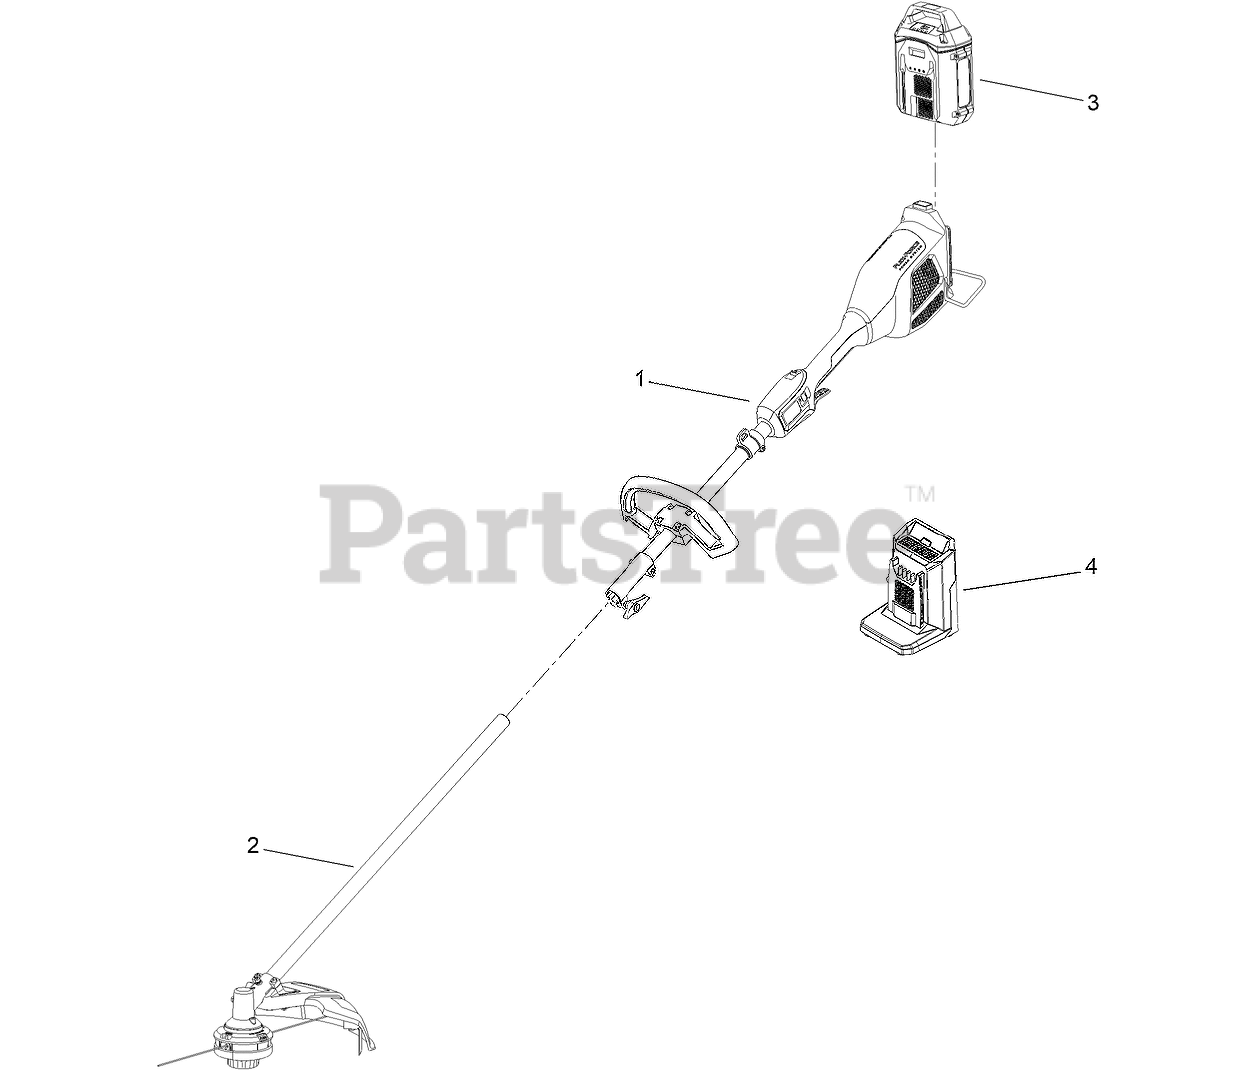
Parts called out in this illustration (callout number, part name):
1	POWER HEAD
2	TRIMMER ATTACHMENT
3	BATTERY-LI ION, 60V 2.5 AH
4	CHARGER-BATTERY, 60V 2 AMP
